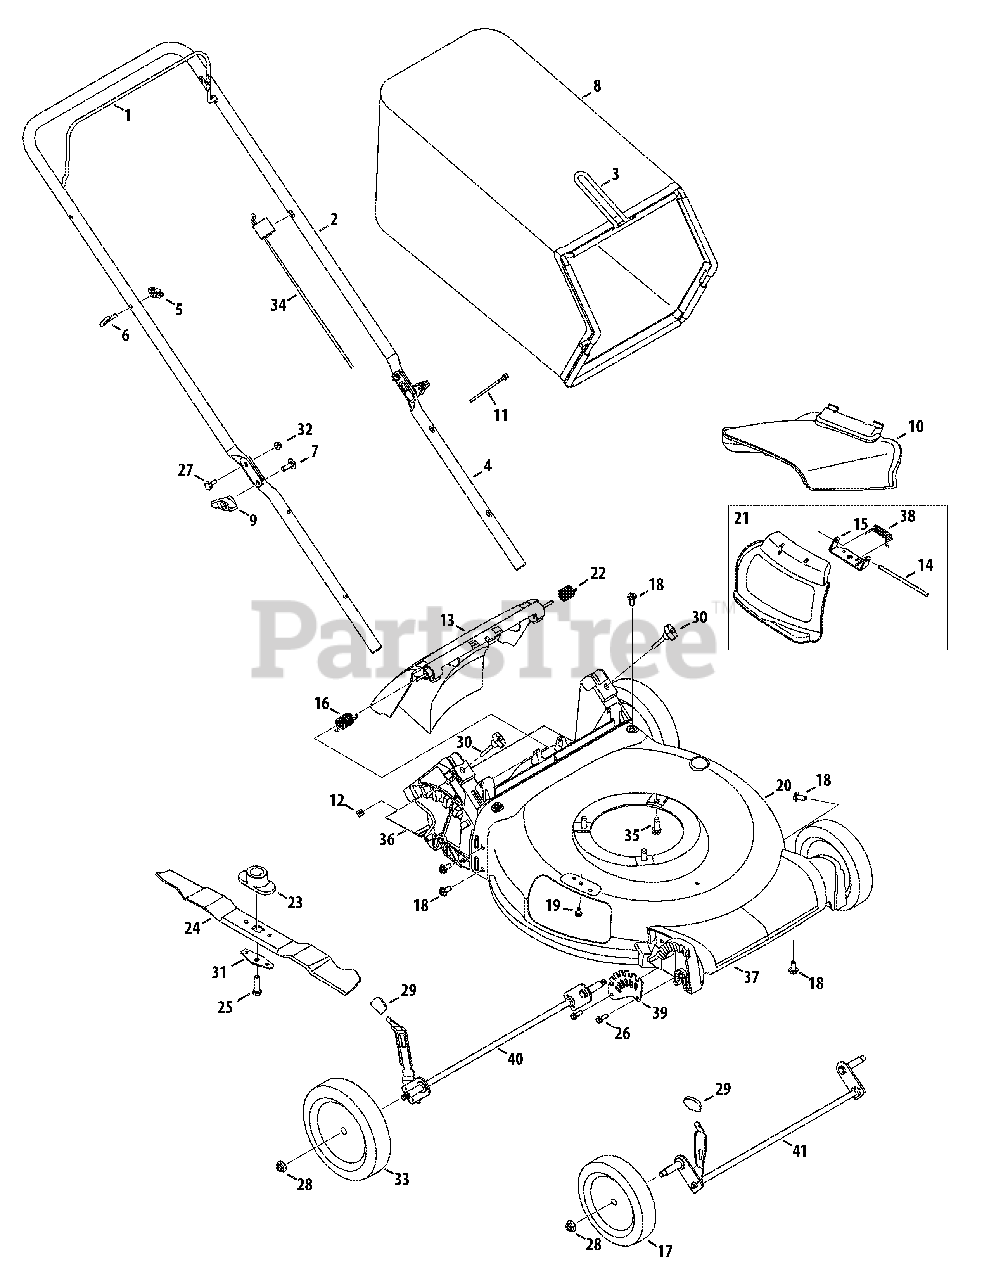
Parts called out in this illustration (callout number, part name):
1	Blade Control
2	Upper Handle
3	Grass Catcher Frame
4	Lower Handle
5	Wing Nut
6	Rope Guide
7	Carriage Screw ,5/16-18
8	Grass Bag
9	Wing Knob
10	Side Chute
11	Cable Tie
12	Nut, Sq., 1/4-20
13	Rear Discharge Door Assembly
14	Hinge Pin
15	Chute Deflector Bracket
16	Torsion Spring - RH
17	Front Wheel
18	Screw, 5/16-14 x .750
19	Screw, 1/4-20 x .500
20	Deck , 21"
21	Hinged Mulch Plug Assembly
22	Torsion Spring - LH
23	Blade Adapter
24	Mulching Blade
25	Screw , 3/8-24 x 1.50
26	Screw, 1/4-15 x .750
27	Sldr. Screw, .375 x .126 x 1/4-20
28	Flange Lock Nut, 3/8-16
29	Adjustment Lever Knob
30	Wing Nut
31	Blade Bell Support
32	Nut, Flange Lock, 1/4-20
33	Rear Wheel
34	Control Cable
35	TT Sems Screw, 3/8-16 x 1.0
36	Trail shield
37	Front Cover
38	Torsion Spring
39	Front Height Adjuster Plate
40	Rear Axle Assembly
41	Front Axle Assembly
